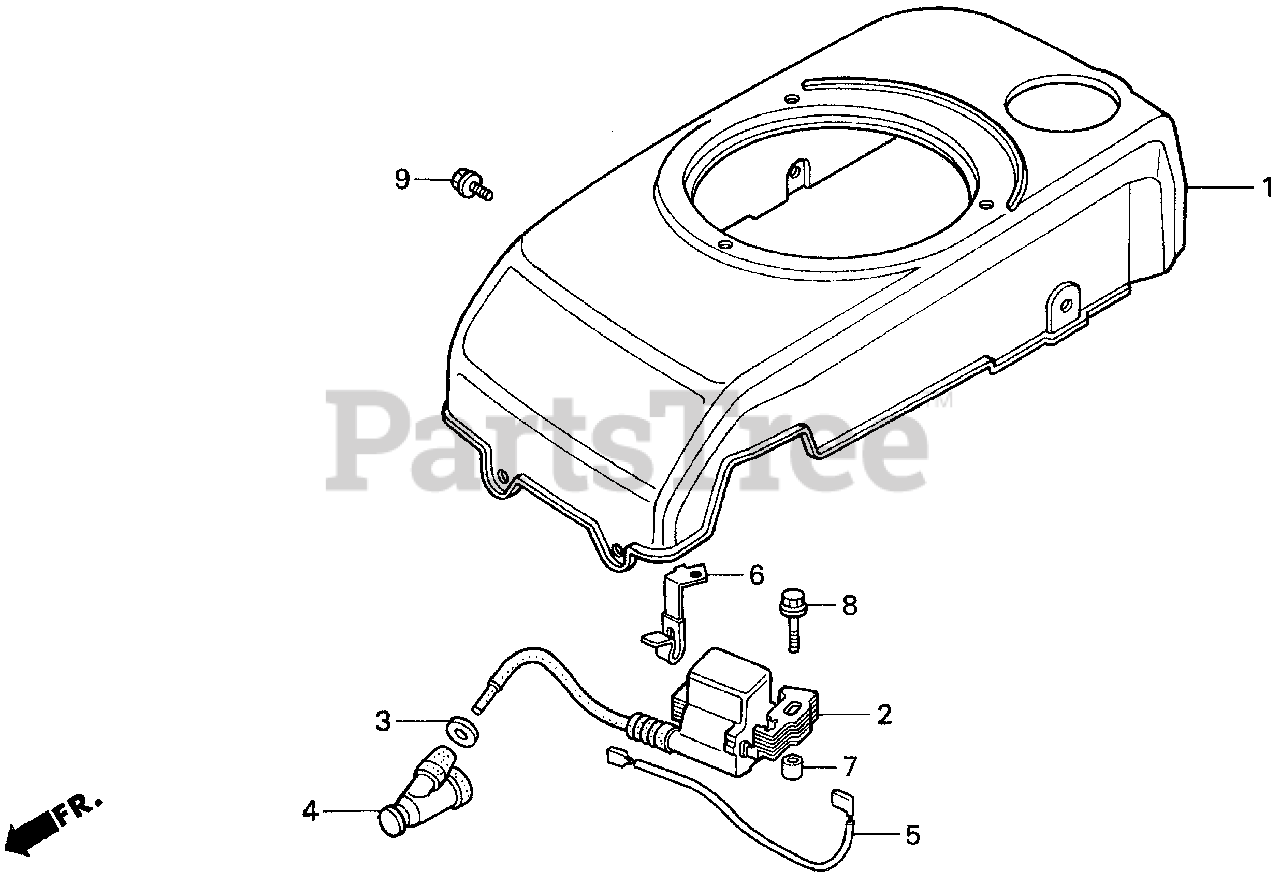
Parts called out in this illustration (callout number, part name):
1	COVER, FAN *R8* (BRIGHT RED)
2	COIL ASSY., IGNITION
3	GROMMET, IGNITION WIRE
4	TERMINAL ASSY., IGNITION
7	COLLAR, ROTO-STOP
8	BOLT, FLANGE (6X35) (CT200)
9	BOLT, FLANGE (6X10)
